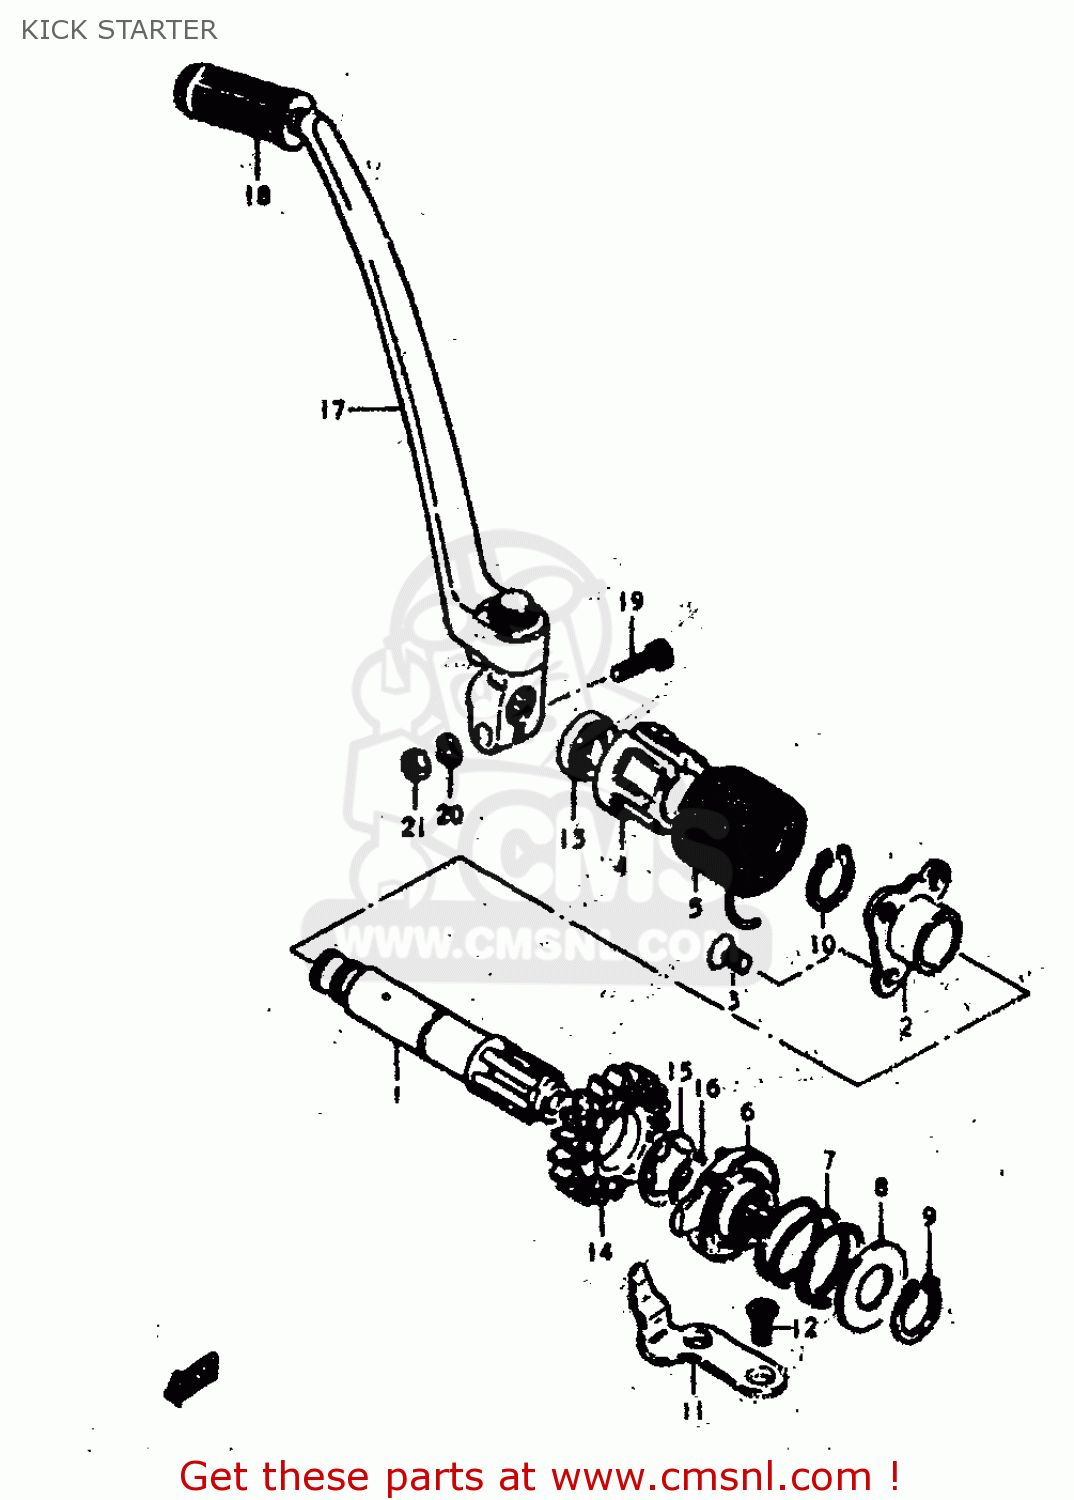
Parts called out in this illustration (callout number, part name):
1	SHAFT,KICK STARTER
2	HOLDER,KICK STARTER SHAFT
3	SCREW
4	GUIDE,STARTER SHAFT SPRING
5	SPRING
6	STARTER,KICK
7	SPRING
8	WASHER
9	CIRCLIP
10	CIRCLIP
11	GUIDE,STARTING SPRING
12	SCREW
13	SEAL,OIL(20X27X5)
14	GEAR,KICK STARTER DRIVE
15	WASHER,LOCK
16	CIRCLIP
17	LEVER ASSY,KICK STARTER
18	RUBBER,KICK STARTER PEDAL
19	BOLT,M10X1.25X
20	LOCK WASHER
21	NUT
